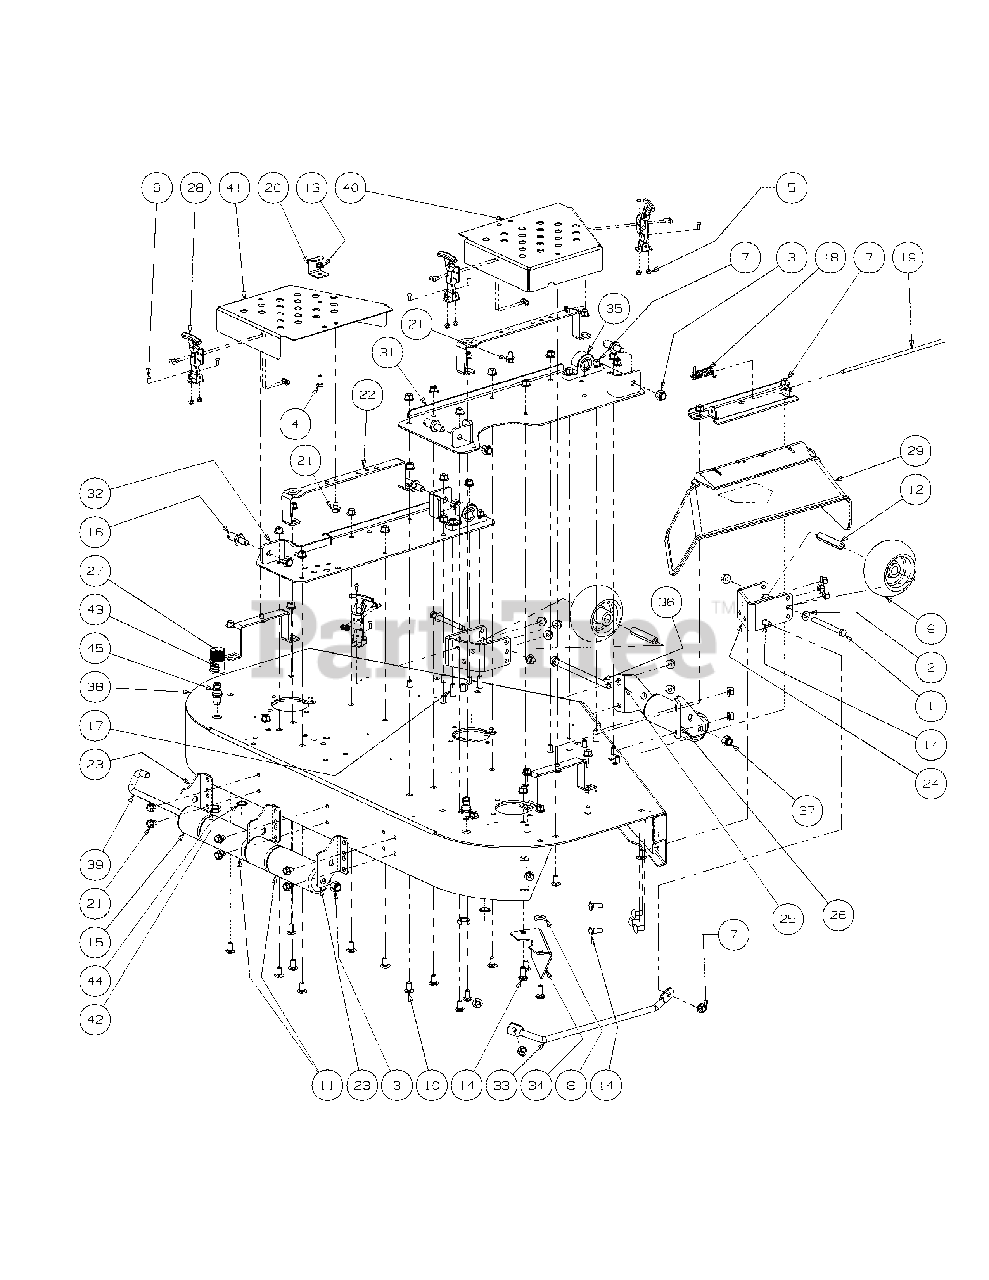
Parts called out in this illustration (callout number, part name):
1	Hex Cap Screw, 3/8-16, 3.75
2	Flat Washer, 3/8
3	Lock Nut, Nylon Insert, 1/2-13
4	Hex Cap Screw, 5/16-18 x 3/4
5	Lock Nut, Nylon Insert, 10-32
6	Phillip Head Screw, 10-32
7	Flange Lock Hex Nut, 3/8-16
8	Idler Washer
9	Complete Wheel, 5.00 Dia
10	Carriage Bolt, 3/8-16 x .75 Lg
11	Front Roller
12	Wheel Spacer
13	Hex Flange Lock Nut, 5/16-18
14	Carriage Bolt, 3/8-16 x 1
16	Pin, 5/8 Dia. x 1.2 Lg.
17	Carriage Screw, 3/8-16 x 1.25
18	Torsion Spring, 0.4 ID x 2.16 LG
19	Chute Deflector Rod
20	Bracket Stop Tension Rod
21	Hex Index Washer Screw, 3/8-16, .05
22	Fabricated Belt Support Cover
23	Fabricted Deck Roller Mount Bracket
24	Front Anti-Scalp Wheel Mount Bracket
27	Outer Belt Cover Support Assembly
28	Latch Drawing, T-Handle
29	Deflector Chute
30	Deflector Chute Bracket
31	Right Hand Deck Bracket Assembly
32	Left Hand Deck Bracket Assembly
33	Fabricated Deck Finger Guard
34	Fabricated Deck, Chute Bracket
35	Pillow Block
36	Hex Cap Screw, 1/2-20 x 7.50
37	Lock Nut, Nylon Insert, 1/2-20
38	48 Fabricated Deck Assembly
39	J-Hook w/ Threaded Roller
40	Right Hand Belt Cover
41	Left Hand Belt Cover
42	Hex Nut, M16-1.5
43	Water Nozzle Adaptor
44	Lock Washer, 17 x 23.8 x 1.95
45	Deck Water Nozzle
